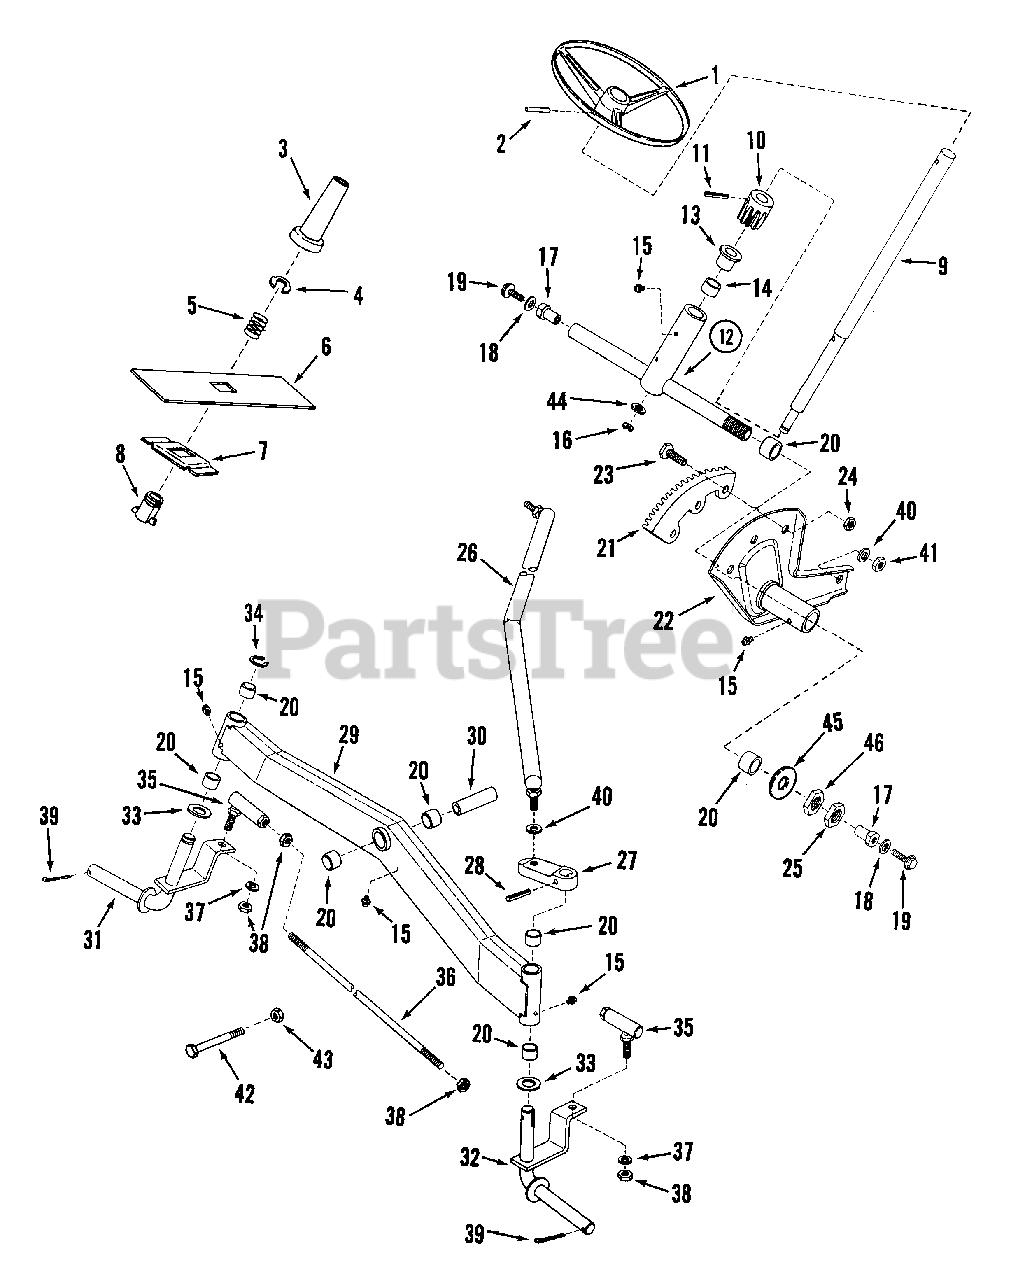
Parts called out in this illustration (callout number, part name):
1	STEERING WHEEL
2	ROLL-PIN, 1/4" x 2-1/4"
3	ACTUATOR, Steering Lock
4	RING, 13/16" External Retaining
5	SPRING, Actuator
6	COVER, Slide
7	RISER, Steering Lock
8	BUSHING, Steering Lock
9	SHAFT, Steering (Current Models)
10	PINION, Steering
11	ROLL-PIN, 3/16 x 1-1/2"
12	ASSEMBLY, Bearing Support
13	BEARING, Flange
14	BUSHING
15	LUBE FITTING, Straight (press-fit for .187 dia. Hole)
16	SNAP-RING, 5/16 (Current Models)
17	PIVOT
18	WASHER, 5/16 Internal Tooth Lock
19	SCREW, 5/16-18 x 3/4" Hex Washer Self-Tap
20	BEARING
21	QUADRANT, Steering
22	ASSEMBLY, Sector
23	SCREW, 1/4-20 x 5/8" Hex Head Cap, Grade 5
24	NUT, 1/4-20 Hex Center Lock, Grade B or 5
25	NUT, 3/4-16 Hex Jam
26	DRAG-LINK
27	ARM, Steering
28	ROLL-PIN, 1/4 x 1-1/4"
29	ASSEMBLY, Front Axle
30	JOURNAL, Axle
31	KING-PIN, Right Side
32	KING-PIN, Left Side
33	WASHER, Thrust
34	RING, 3/4" External Retaining
35	BALL JOINT, 3/8-24 Thread
36	TIE-ROD
37	WASHER, 3/8" Split Lock
38	NUT, 3/8-24 Hex, Grade 2
39	COTTER-PIN, 5/32 x 1"
40	WASHER, 1/2 Split Lock
41	NUT, 1/2-20 Hex, Grade 2
42	SCREW, 1/2-20 x 4" Hex Head Cap, Grade 5
43	NUT, 1/2-20 Hex Thin Lock
44	WASHER, 3/8" Flat
45	WASHER, 3/4" I.D. Flat
46	NUT, 3/4-16 Hex
